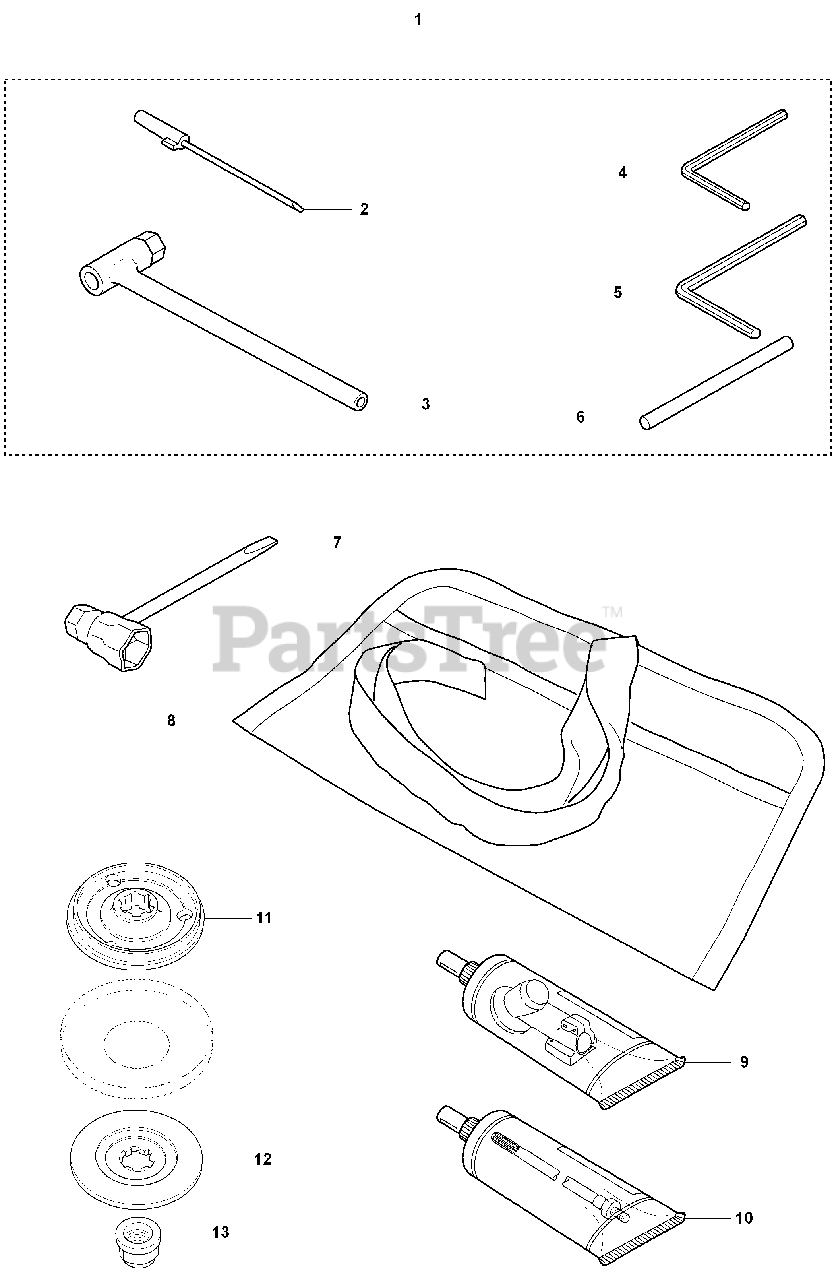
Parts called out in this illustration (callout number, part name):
2	SCREWDRIVER
4	L-KEY WRENCH
5	KEY
6	LOCKING PIN
7	COMBI TOOL
9	BEVEL GEAR GREASE
11	CARRIER
12	SUPPORT FLANGE
13	BLADE NUT
